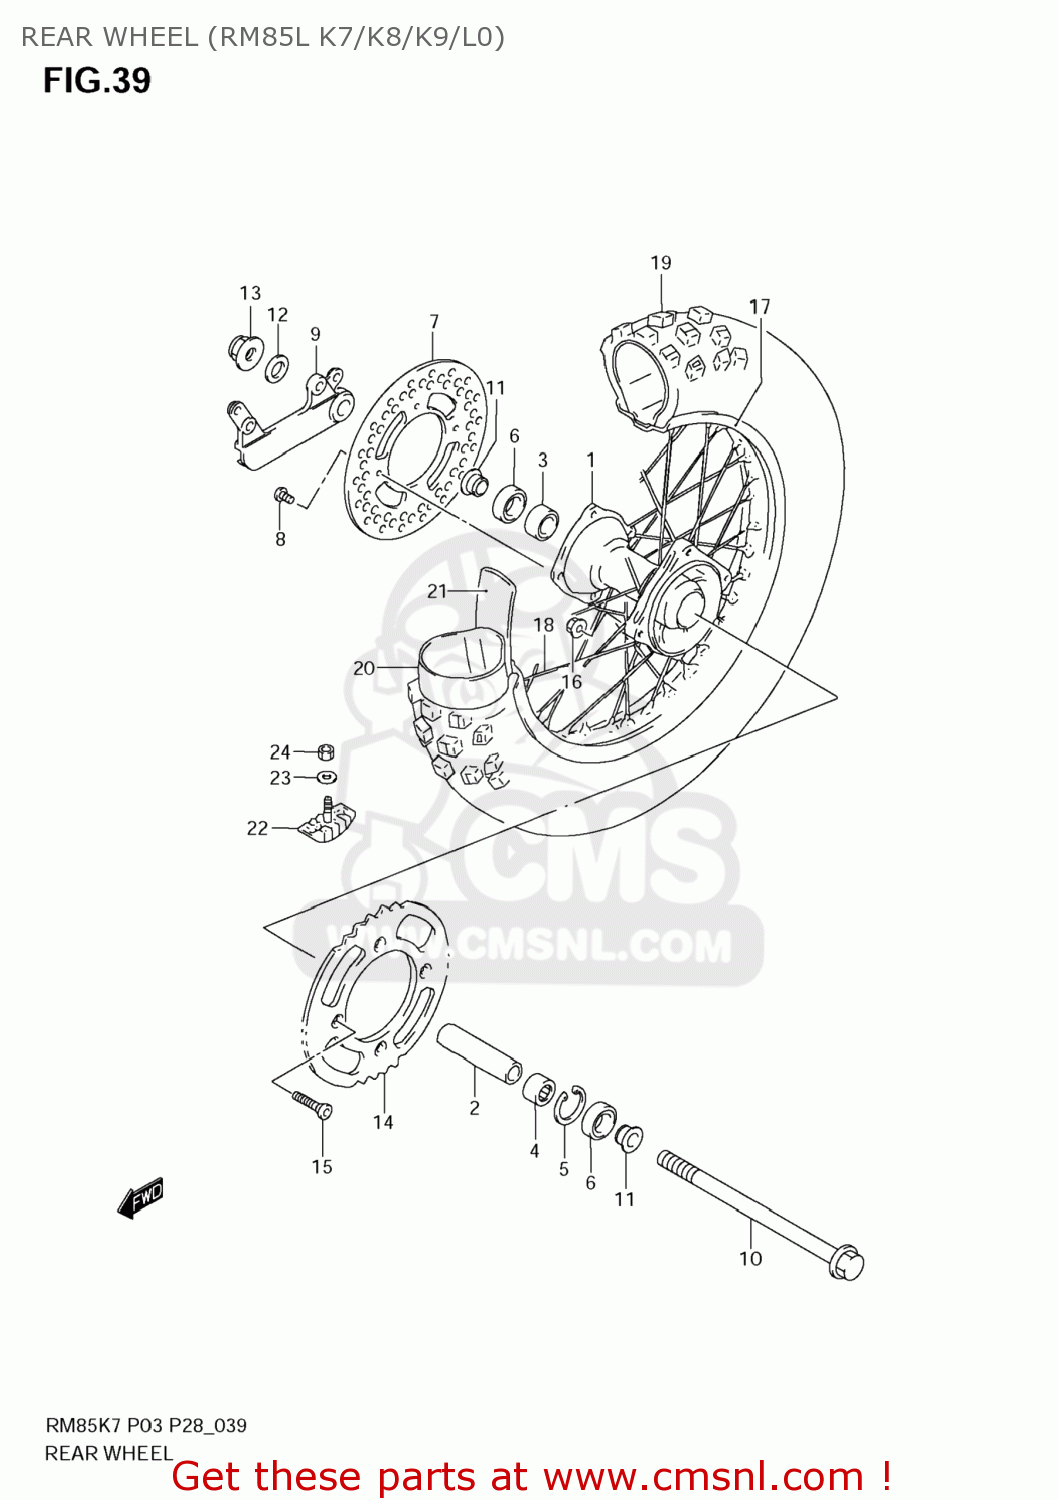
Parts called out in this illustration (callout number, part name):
1	HUB,RR WHEEL
2	SPACER,RR HUB BEARING
3	BEARING
4	BEARING(15X35X11)
5	CIRCLIP
6	SEAL,OIL(20X35X7)
7	DISC,RR BRAKE
8	SCREW
9	BRACKET,RR CALIPER
10	AXLE,RR
11	SPACER,RR AXLE
12	WASHER(14.5X30X3.2)
13	NUT
14	SPROCKET,RR(47T)
15	BOLT(8X30.5)
16	NUT
17	RIM,RR WHEEL(1.60X16 AL)
18	SPOKE SET,RR WHEEL
19	TIRE,RR(90/100 16 52M D737)
20	TUBE ASSY,WHEEL INNER
21	PROTECTOR, INNER TUBE
22	STOPPER,BEAD(1.85)
23	WASHER
24	NUT
